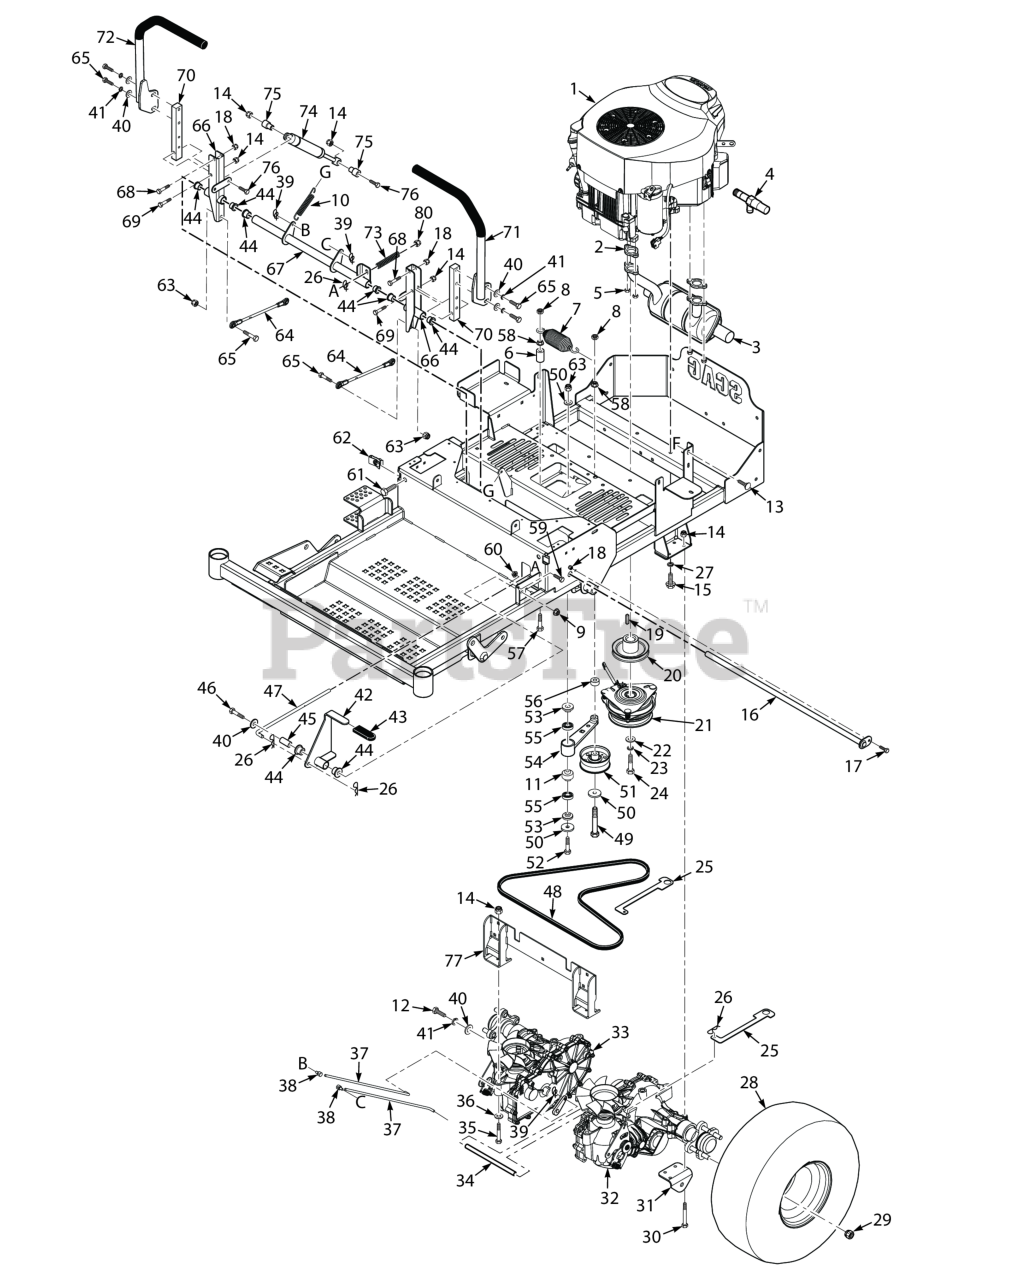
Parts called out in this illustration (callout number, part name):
1	Engine, Briggs & Stratton PXi2500
2	Gasket, Exhaust
3	Muffler, Kawasaki FR651V & FR691V
4	Oil Drain, Kawasaki
5	Nut, M8 x 1.25 Hex Special
6	Spacer, Idler Pulley - SFZ52
7	Spring, Transmission Drive
8	Bolt, Hex Head 3/8-16 x 1" Ser. Flg.
9	Nut, Flange Elastic Stop Nut, 3/8-16
10	Spring, Deck Latch
11	Spacer, Bearing
12	Bolt, Hex Head 3/8-16 x 2-1/4" - 61"
13	Serr. Fl. Hex Head CPSCR, 1/4-20 x 3/4"
14	HEX NUT, ELASTIC STOP LOCK, 5/16-18
15	Bolt, Hex Head 3/8-16 x 1-1/4", Kawasaki FX / FT & FT-EFI
16	Shaft Weldment, Control Arm
17	BOLT, HEX HEAD, 1/4-20 X 5/8
18	HEX, NUT, ELASTIC STOP LOCK, 1/4-20
19	Key, 1/4 x 1/4 x 3" (61H)
20	Pulley, 4-1/2" - 1.125" Bore (SZL-61)
21	Electric Clutch Assembly - SFZ52 & SFZ61
22	Flatwasher, 7/16-.469 x 1.75 x .25 (48, 52)
23	Lockwasher, 7/16� Spring
24	Bolt, Hex Head 7/16-20 x 3¼" w/Patch
25	Lever, Dump Valve
26	HAIR PIN, .08 DIAMETER X 1-3/16"
27	Lockwasher, 3/8" Spring, Kawasaki FX / FT & FT-EFI / B&S 32BV
28	WHEEL ASSY, 20 X 10-10
29	Wheel Nut, 1/2-20 x 13/16
30	Bolt, Hex Head 5/16-18 x 3.00"
31	Bracket, Push Arm Link
32	Transaxle, LH - SZL-61
33	Transaxle, RH - SZL-61
34	Spacer
35	BOLT, HEX HEAD, 5/16-18 X 2-1/4
36	Flatwasher, 5/16-.375 x .875 x .083 (35BV & 37BV-EFI)
37	Rod, Brake
38	Joint, Swivel
39	Pin, Rue Cotter 3/8" Diameter
40	Flatwasher, 3/8" Special (.391 x .938 x .105)
41	Lockwasher, 3/8" Spring, Kawasaki FX / FT & FT-EFI / B&S 32BV
42	Brake Lever Assembly
43	Grip, Brake Handle
44	Bearing
45	Pivot, Brake Lever
46	Capscrew, Hex Head 3/8-16 x 2-1/2"
47	Rod, Upper Brake Linkage
48	Belt, Transmission -SZL
49	Capscrew, Hex Head 3/8-16 x 3-3/4"
50	Flatwasher, 3/8 (.391 x .938 x .105 HD) Grade 8
51	Pulley, 3-1/2" Dia.
52	Bolt, Hex Head 3/8-16 x 3" - 52"
53	Spacer, Controls
54	Trans. Idler Arm Assy. (Includes 24, 79)
55	BEARINGS, BALL, NEUTRAL RETURN
56	Spacer, Idler Pulley - SFZ61
57	Capscrew, Hex Head 3/8-16 x 2.0"
58	NUT, 3/8-16 SERRATED FLANGE HEX HEAD
59	Capscrew, Hex Head 1/4-20 x 1"
60	NUT, 1/4-20 SERRATED FLANGE HEX HEAD
61	Bolt, Hex Head 3/8-16 x 2-1/2" Soecial Lock
62	U-Nut, 3/8-16
63	HEX NUT, ELASTIC STOP LOCK, 3/8-16
64	Linkage, Pump
65	Bolt, Hex Head 3/8-16 x 1-1/4", Kawasaki FX / FT & FT-EFI
66	Control Arm Assembly
67	Bellcrank Assembly (incl. 44)
68	Bolt, Hex Head, 1/4-20 x 1-1/4"
69	Bolt, Hex Head 5/16-18 x 1-1/2" - Front
70	Bar, Control Lever
71	Handlebar w/Grip
72	Handlebar w/Grip
73	Spring, Brake
74	Damper, Steering
75	Spacer, Pump Dampener
76	Bolt, Hex Head 5/16-18 x 1-1/2" (Right Front Engine Mounting, Briggs and Kohler Only)
77	Mounting Weldment, Axle - Hydro-Gear
